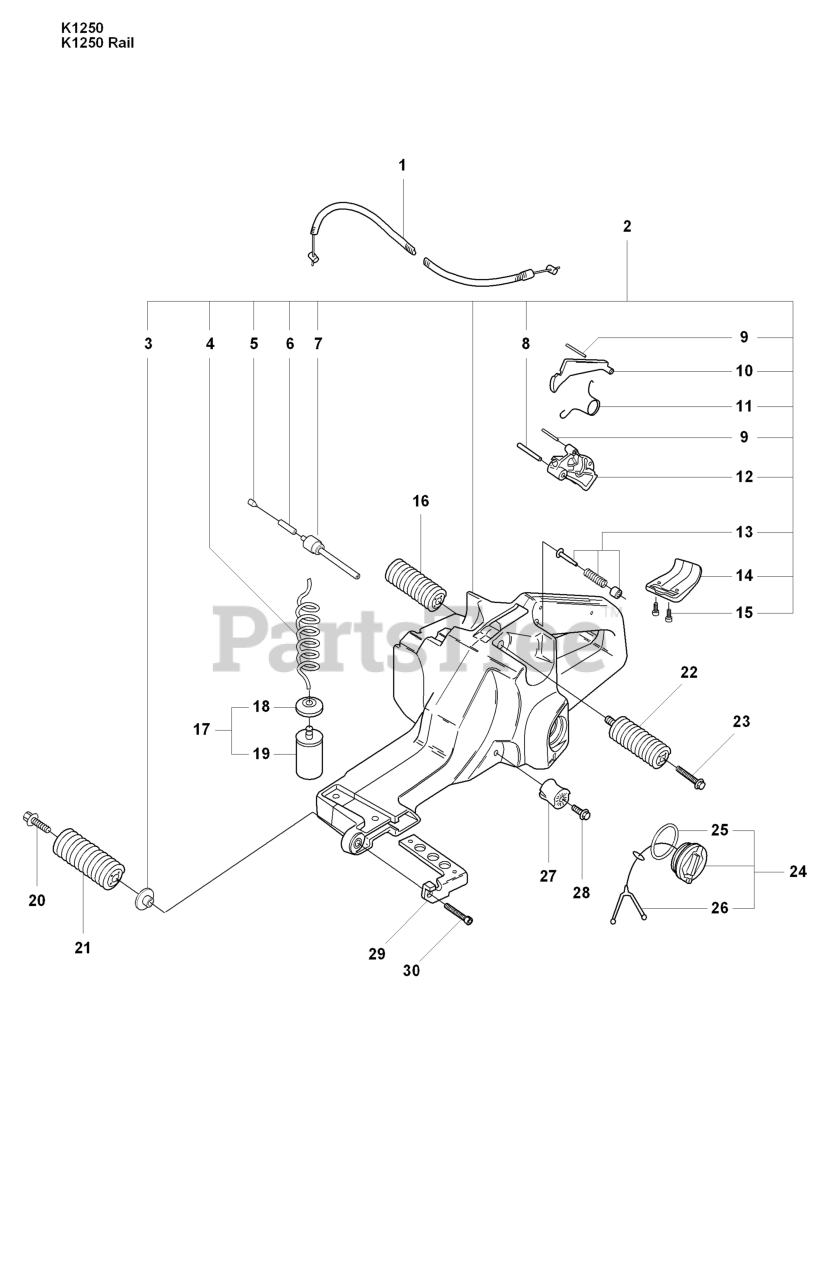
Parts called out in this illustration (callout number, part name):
1	THROTTLE WIRE
2	TANK COMP
4	HOSE
5	SINTER PLUG
6	FUEL HOSE
7	TANK VENT
8	PIN 4 X 35
9	PIN 3X25
10	THROTTLE CATCH
12	THROTTLE LEVER
13	THROTTLE CATCH,KIT
16	ANTIVIBE ELEMENT
17	FILTER
21	ANTIVIBE ELEMENT
22	ANTIVIBE ELEMENT
23	SCREW MC6S 6X16
24	TANK CAP ASSY
27	ANTIVIBE ELEMENT
28	SCREW
